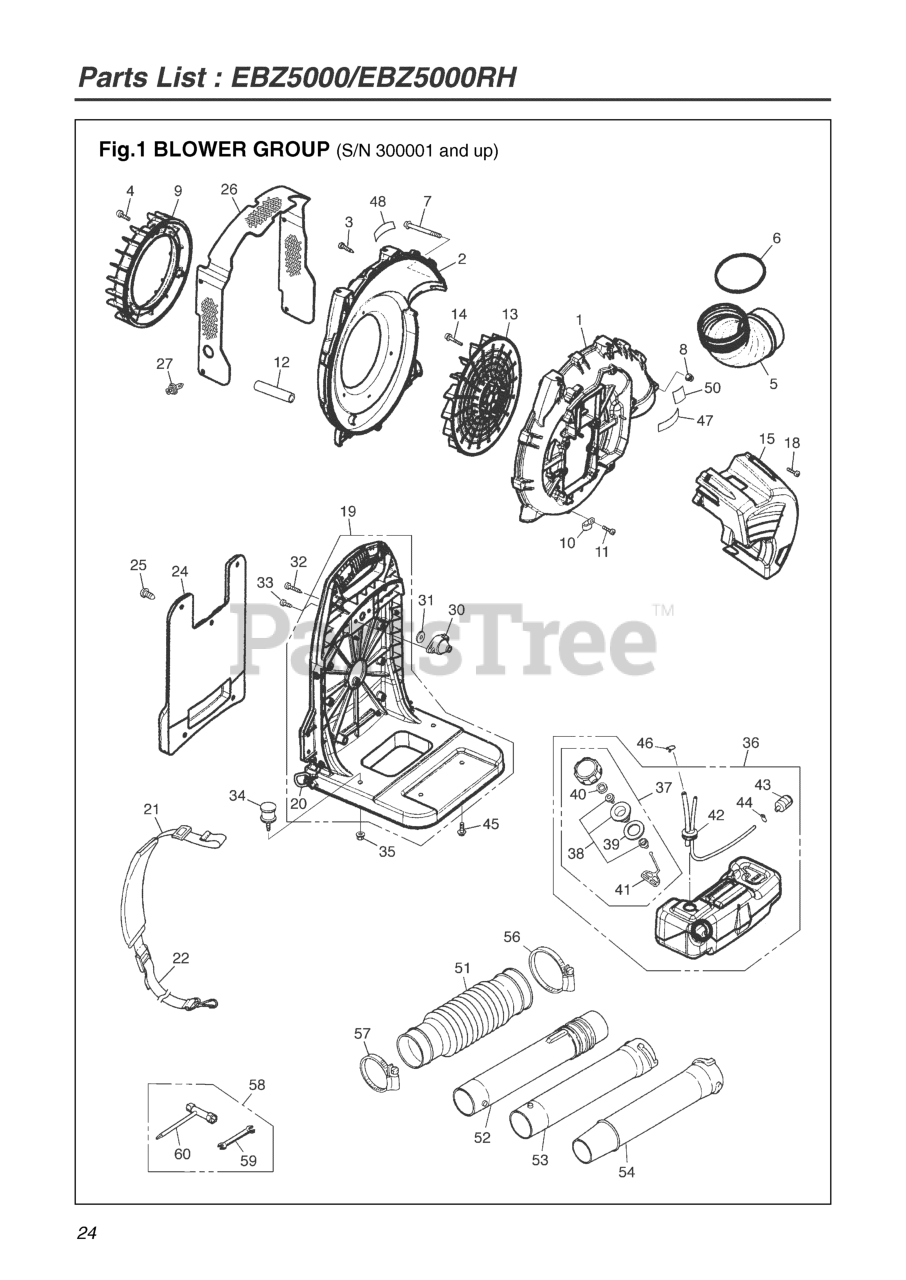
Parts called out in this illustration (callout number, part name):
1	CASE, VOLUTE
2	VOLUTE COVER(RPLS.T4017-31210)
3	SCREW
4	SCREW
5	ELBOW
6	O-RING
7	SCREW TORX
8	NUT (B)
10	CLAMP (RPLS 1140-72231)
12	TUBE (RPLS. 07270-01507)
13	FAN
14	BOLT
15	ENGINE COVER
18	SCREW
19	FRAME COMPLETE
20	RING (REPLACES -21120)
21	USE T4017-32310
24	PAD
25	CLIP (RPLS 3490-21320)
26	NET COMPLETE
27	CLIP
30	DAMPER, UPPER
31	WASHER
32	SCREW (RPLS T4970-54010)
33	SCREW TORX
34	DAMPER, LOWER
35	NUT, M6
36	TANK ASSEMBLY
37	CAP ASSY (RPLS -85201)
38	HOLDER (REPLACES -85230)
39	PACKING
40	FILTER
41	STOPPER
42	PIPE COMP.(RPLS 2756-85300)
43	FILTER ASSY
44	CLIP (REPLACES 2841-31280)
45	SCREW TORX
46	CLIP
47	LABEL, CAUTION (RPLS -31910)
48	LABEL, NET
50	LABEL, LOWNOISE
51	HOSE
52	SWIVEL-JOINT (REPLACES -51200)
53	PIPE, STRAIGHT
54	PIPE, END
56	CLAMP
57	CLAMP (RPLS 3050-13230)
59	SPANNER, 8 X 10 (RPLS 2540- )
